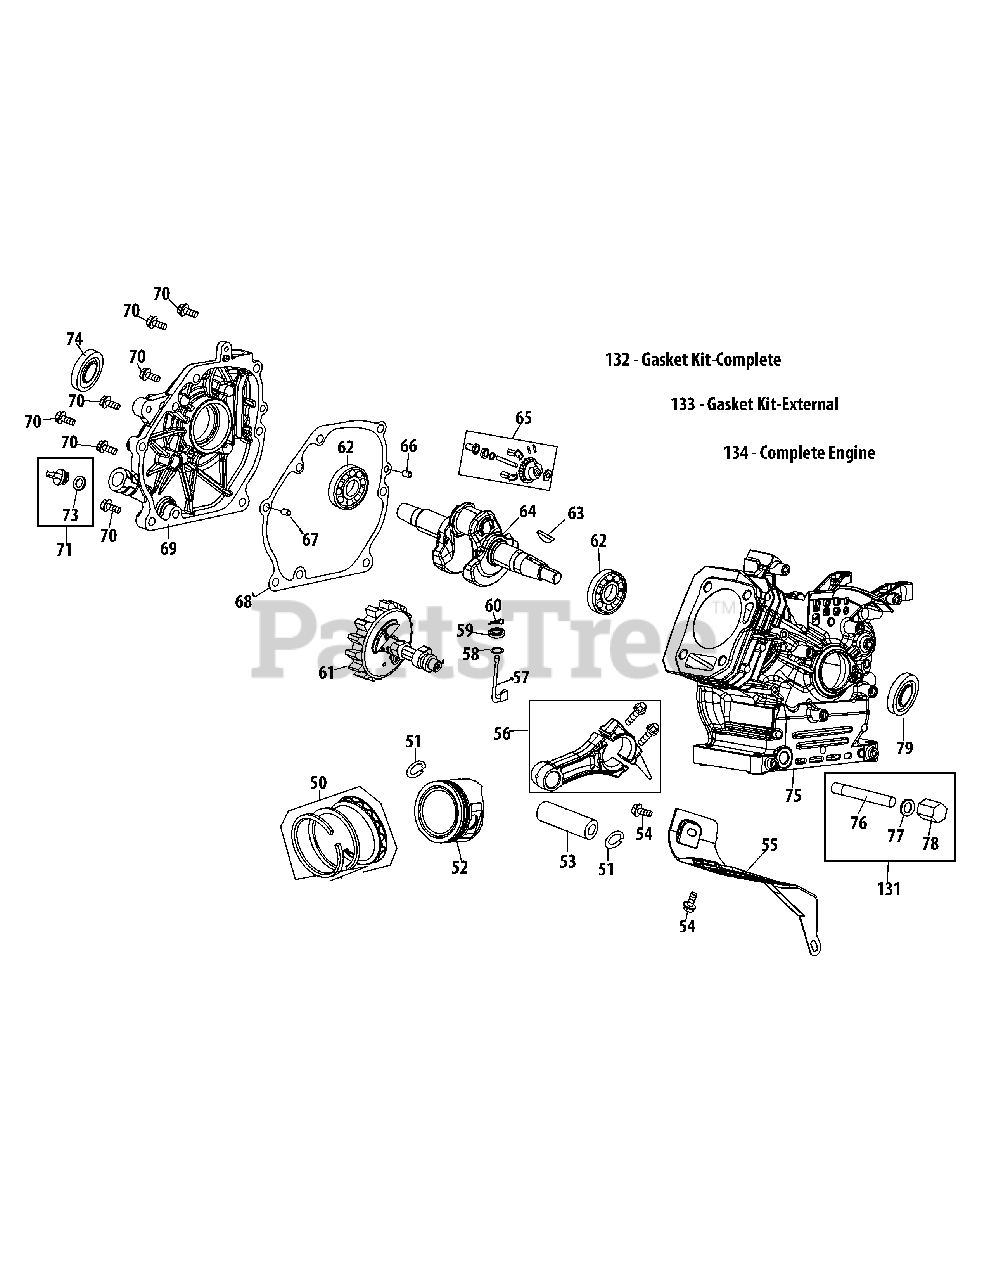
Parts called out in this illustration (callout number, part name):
50	Piston Ring Set
51	Piston Pin Snap Ring
53	Piston Pin
54	Bolt M6×12
55	Air Shield
56	Connecting Rod Assembly
57	Governor Arm Shaft
58	Washer 5.2×1.9
59	Governor Seal
60	Cotter Pin
61	Camshaft Assembly
62	Radial Ball Bearing, 6205
63	Woodruff Key
64	Crankshaft Kit
65	Governor Gear/Shaft Assembly
66	Dowel Pin 7×14
67	Dowel Pin 9×14
68	Crankcase Cover Gasket
69	Crankcase Cover
69	Crankcase Cover Kit
70	Bolt M8×32
71	Oil Fill Plug Assembly
73	O-Ring 15.8×2.5
74	Oil Seal, 25×41.25×6
75	Crankcase Kit
75	Short Block Assembly
76	Oil Drain Pipe Assy.
77	Washer 10×16×1.5
78	Oil Drain Plug
79	Oil Seal 25×41.25×6
131	Oil Drain Assembly
132	Gasket Kit - Complete
133	Gasket Kit - External
134	Complete Engine
